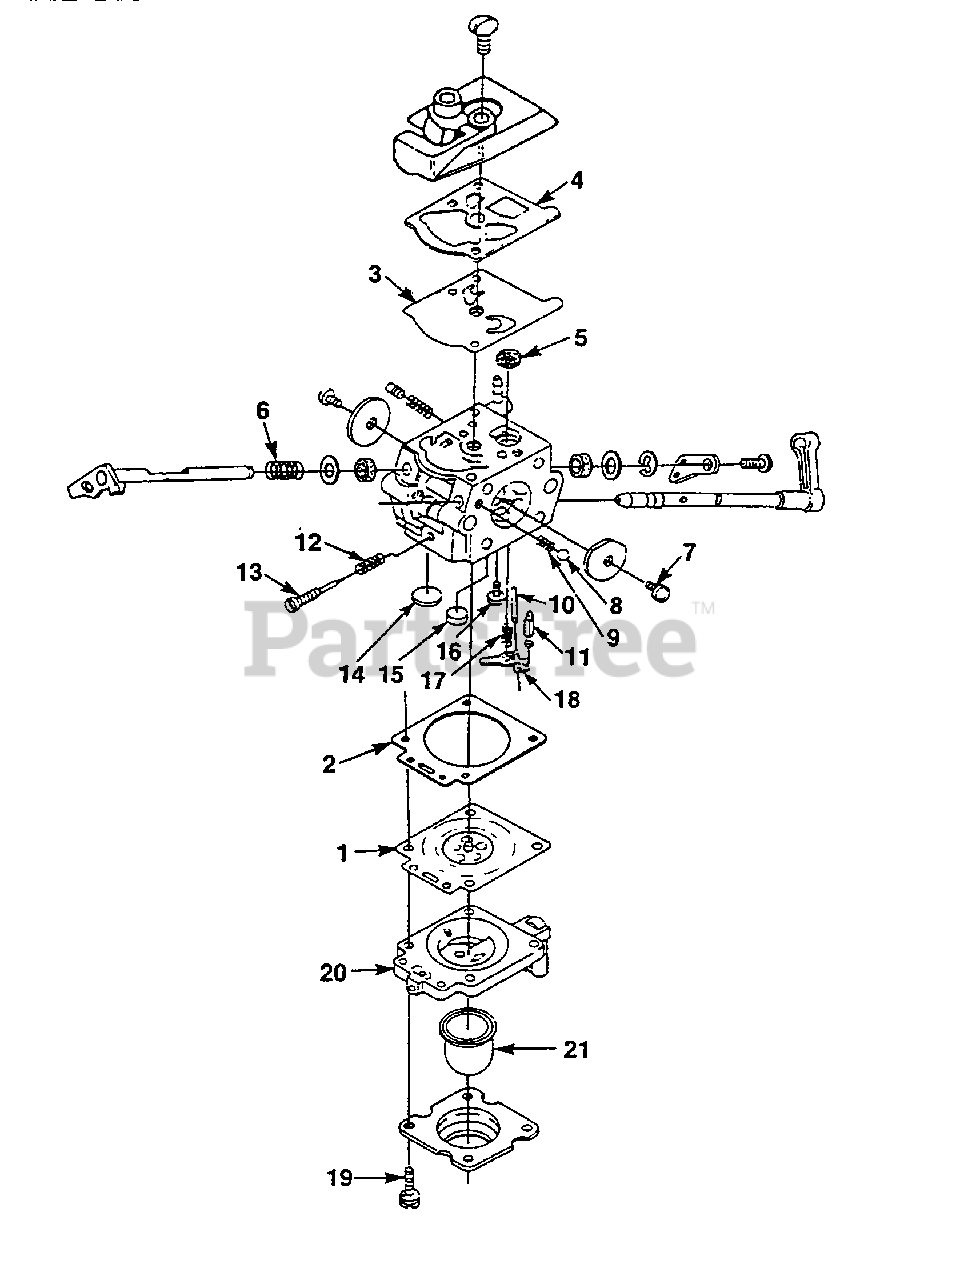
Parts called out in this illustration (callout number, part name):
1	Repair Kit
1	Gasket/Diaphragm Kit
2	Repair Kit
2	Gasket/Diaphragm Kit
3	Repair Kit
3	Gasket/Diaphragm Kit
4	Repair Kit
4	Gasket/Diaphragm Kit
5	Repair Kit
6	Repair Kit
7	Repair Kit
8	Repair Kit
9	Repair Kit
10	Repair Kit
11	Repair Kit
12	Repair Kit
13	Repair Kit
14	Repair Kit
15	Repair Kit
16	Repair Kit
17	Repair Kit
18	Repair Kit
19	Repair Kit
20	Primer Base
21	Primer Bulb
